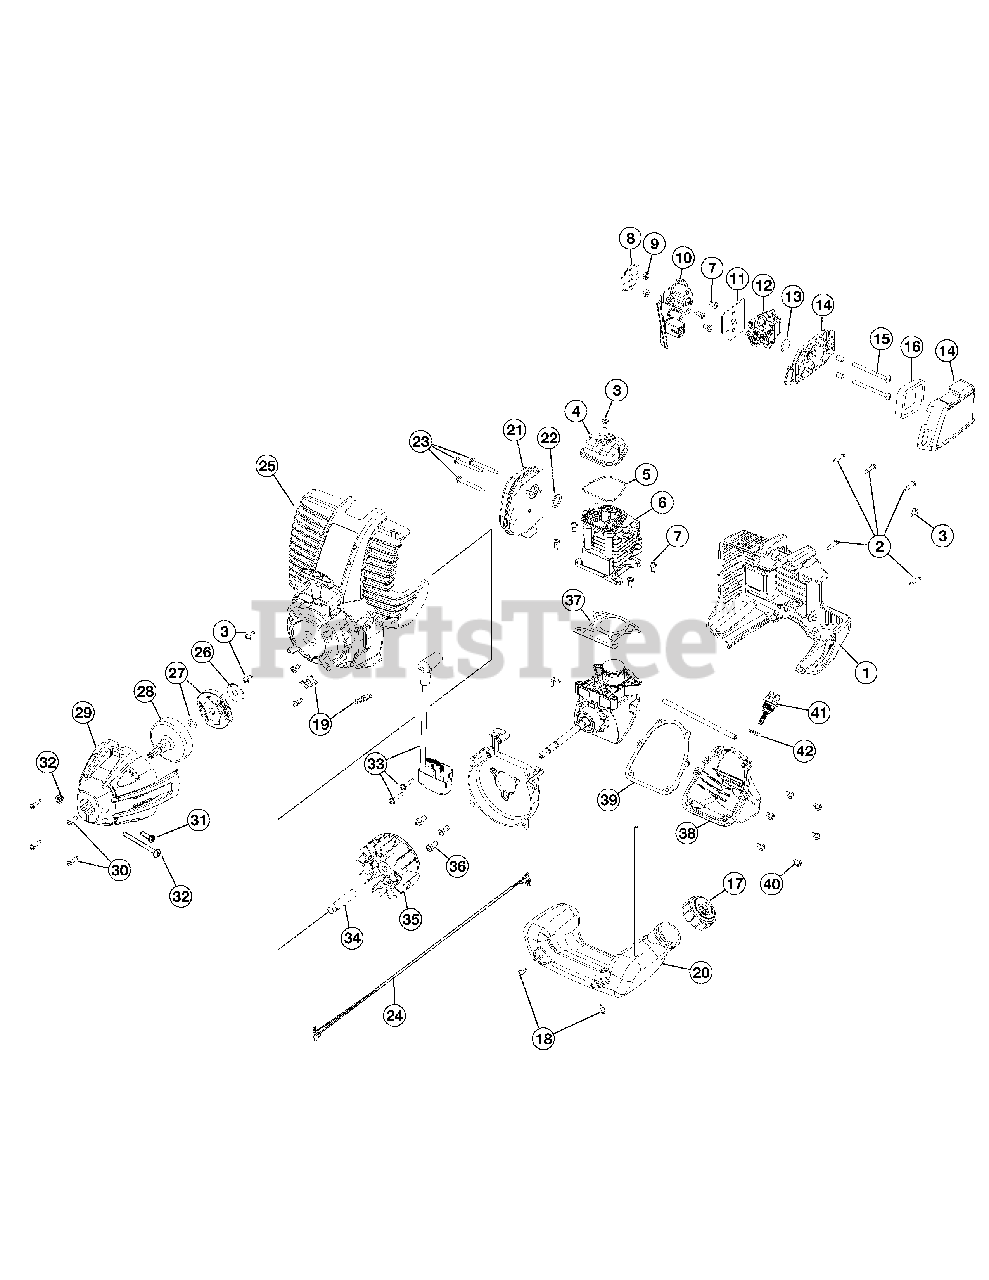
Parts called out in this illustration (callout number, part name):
1	Engine Cover
4	Valve Cover
5	Valve Cover Gasket
6	Cylinder Assembly (Incl. Ref No. 5, 7 & 37)
7	Cylinder Screw
8	Insulator Gasket
10	Insulator (Incl. Ref No. 11)
11	Carburetor Gasket
12	Carburetor w/Primer
13	Carburetor O-Ring
14	Air Filter Cover Assembly (Incl. Ref No. 16)
15	Air Filter Mounting Screw
16	Air Filter
20	Fuel Tank Assembly (Incl. Ref No. 17)
21	Muffler Assembly (Incl. Ref No. 22 & 23)
22	Muffler Gasket
23	Muffler Mounting Screw
25	Starter Housing Assembly (Incl. Ref No. 3)
27	Clutch Assembly
28	Clutch Drum
29	Clutch Cover Assembly (Incl. Ref No. 30-32)
30	Cover Screw
31	Anti-Rotation Screw
32	Clamping Screw Assembly
33	Ignition Module Assembly
36	Shroud Screw
37	Cylinder Gasket
38	Oil Pan (Incl. Ref No. 39 & 40)
39	Oil Pan Gasket
40	Oil Pan Screw
41	Dipstick Assembly (Incl. Ref No. 42)
43	Rope Guide w/Cap
